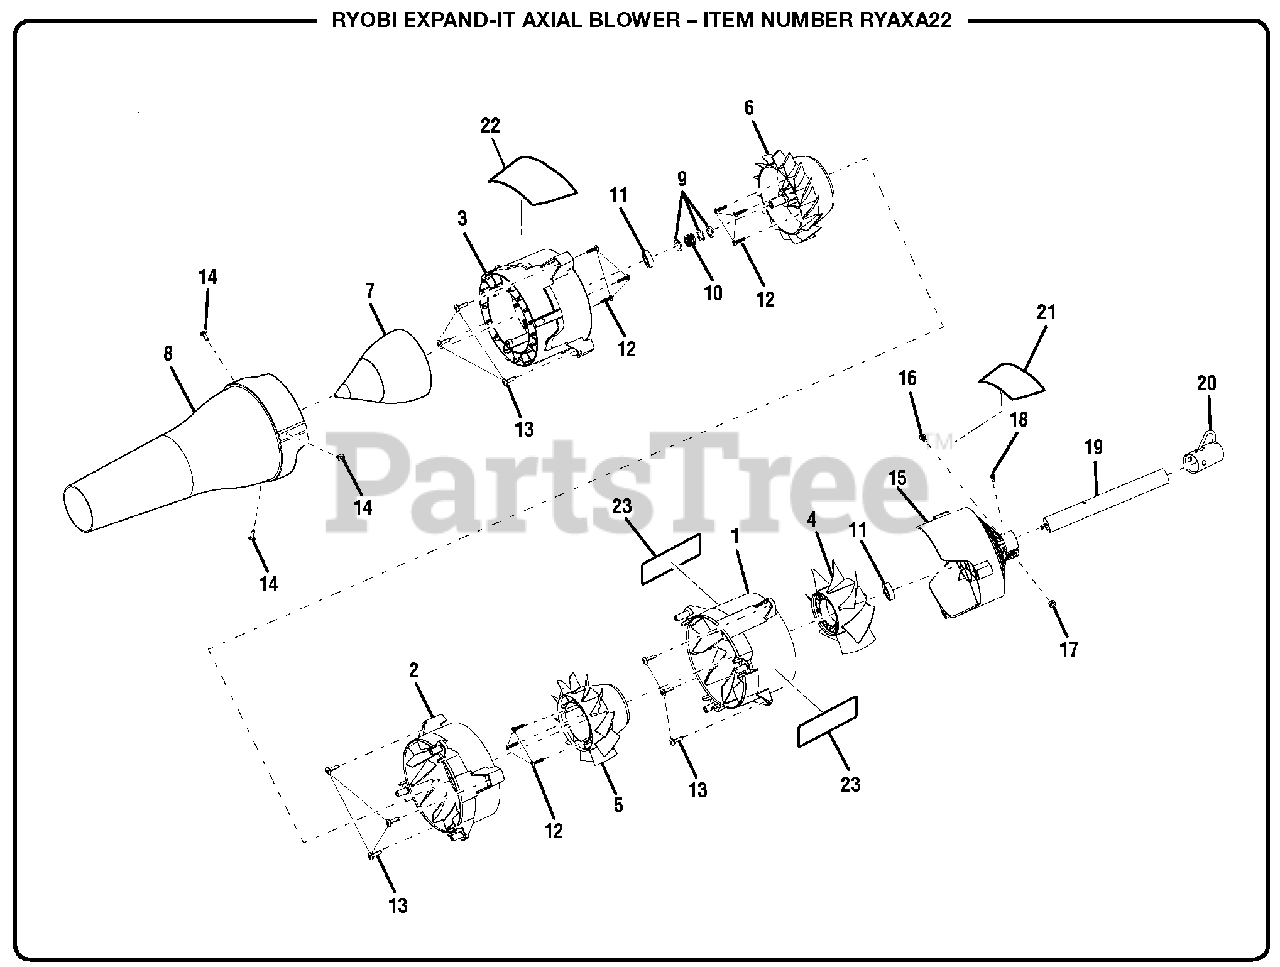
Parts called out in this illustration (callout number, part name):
1	Axial Stator (Stage One)
2	Axial Stator (Stage Two)
3	Axial Stator (Stage Three)
4	Axial Fan (Stage One)
5	Axial Fan (Stage Two)
6	Axial Fan (Stage Three)
7	Reducer Cone
8	Reducer Nozzle
9	Washer (OD18 x ID12.15 x 1.5t)
10	Wave Spring
11	Ball Bearing (6001-ZZ)
12	Screw (M4 x 18 mm, T20 Torx Pan Hd.)
13	Screw (10-14 x 19 mm, T25 Torx Truss Pan Hd. T.F.)
14	Screw (10-14 x 13 mm, T25 Torx Truss Pan Hd. T.F.)
16	Screw (M6 x 12 mm, T27 Torx Pan Hd.)
17	Hex Nut (M6 x 1)
18	Screw (M4 x 8 mm, T20 Torx Pan Hd.)
19	Boom Assembly
20	End Cap
21	Logo Label
22	Safety Icon Label
23	Jet Fan Logo Label
